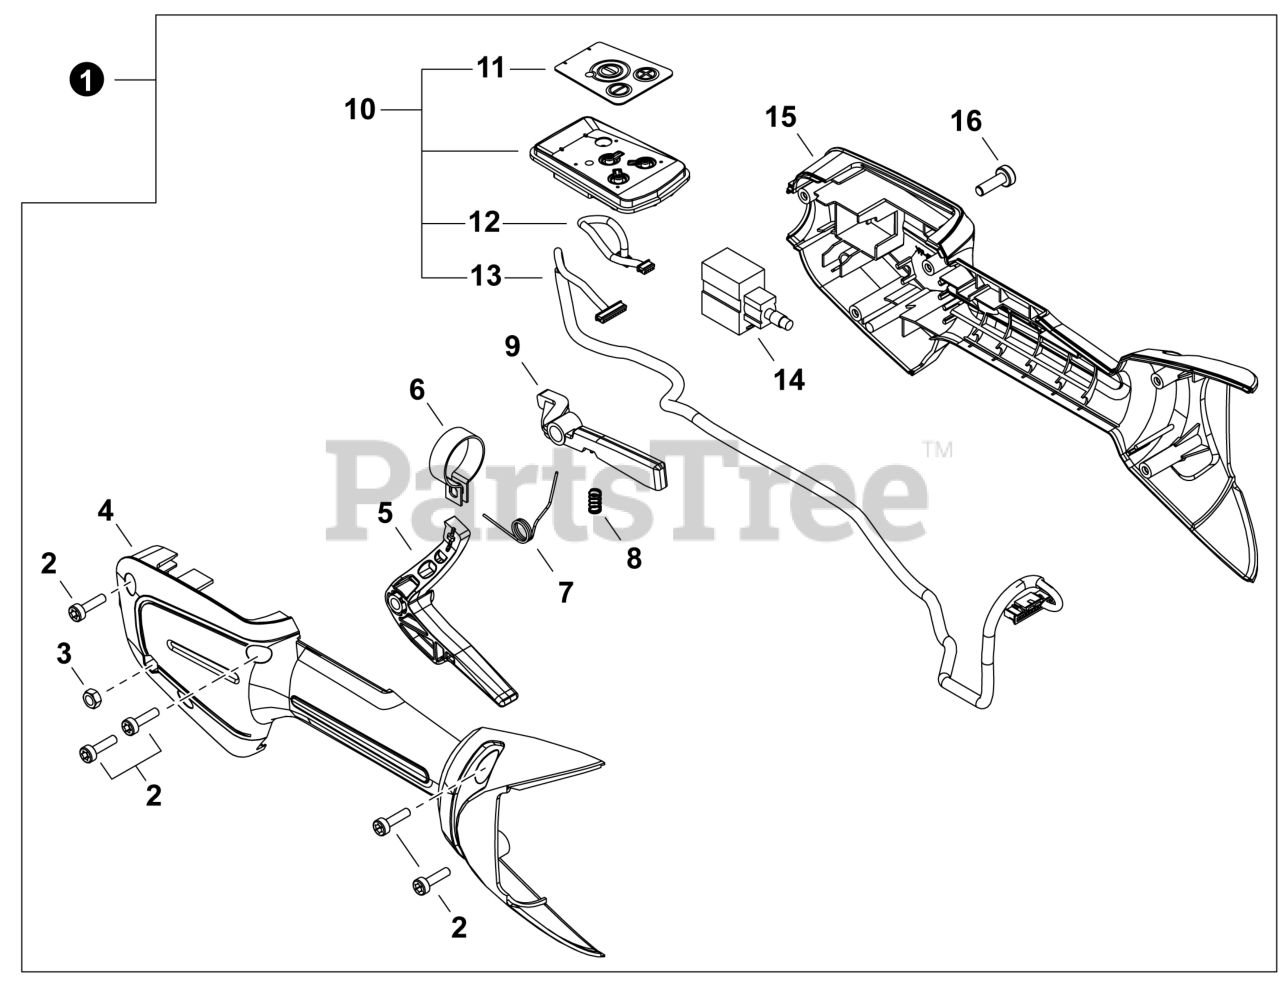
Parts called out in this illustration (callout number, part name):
1	CONTROL HANDLE ASSY
2	BOLT, TORX 4x16
4	GRIP, HANDLE - LEFT
5	TRIGGER, THROTTLE
7	SPRING, TORSION
8	SPRING, COIL
9	LOCKOUT, THROTTLE
10	SWITCH ASSY, ON-OFF
11	LABEL - SWITCH
12	WIRE HARNESS - TRIGGER
13	WIRE HARNESS - MAIN
14	SWITCH, SPEED CONTROL
15	GRIP, HANDLE - RIGHT
16	BOLT, TORX 5x16
